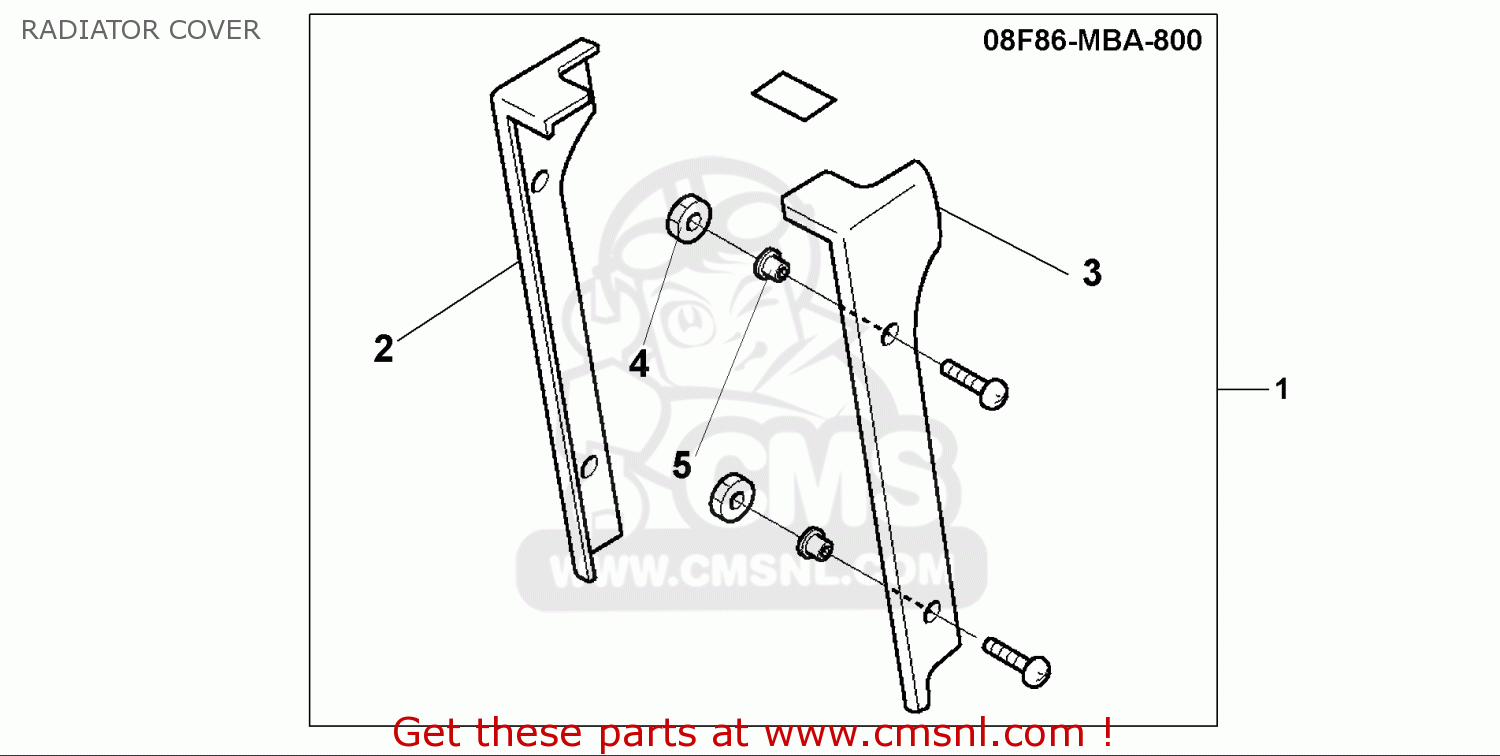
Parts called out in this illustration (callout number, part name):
1	RADIATOR COVER
2	RIGHT RADIATOR COVER
3	LEFT RADIATOR COVER
4	COLLAR,HEADLIGHT
5	NUT,HEX,6MM
